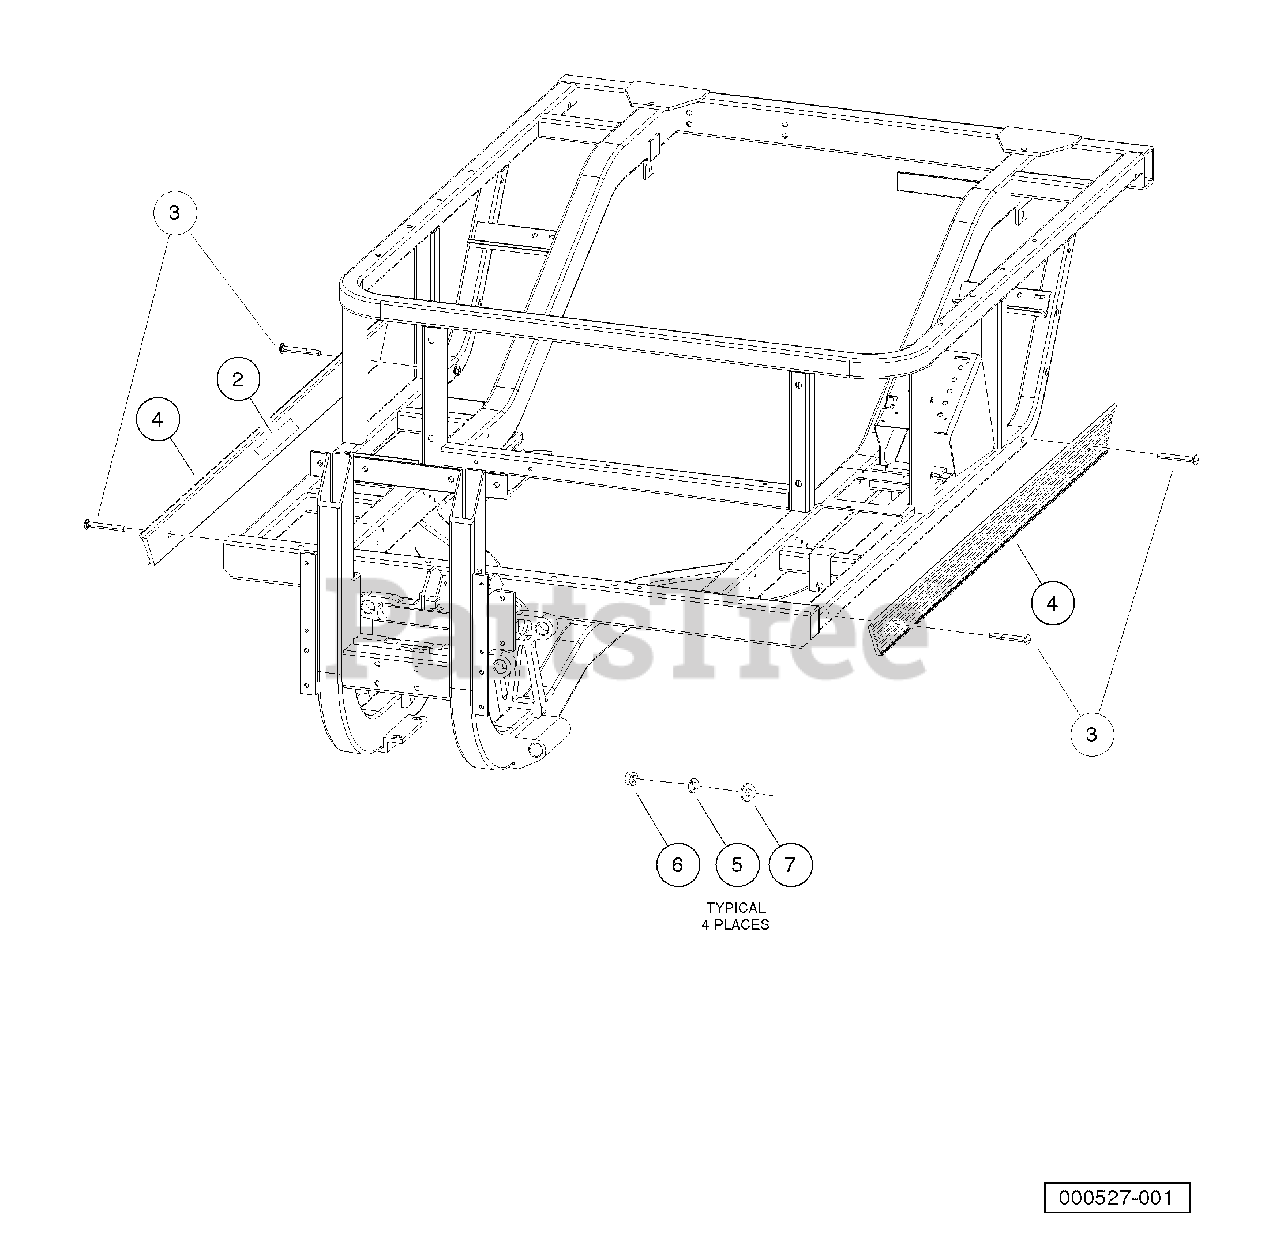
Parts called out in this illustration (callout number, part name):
1	Instl, Stringer, Black
2	Tape, 3M VHB 4950
3	Bolt, 3/8-16 X 3, Carriage Blk
4	Stringer, Side, 134925, Black
5	Washer, Lock, Hel Sp 3/8 Reg
6	Nut, Hex 3/8-16
7	Washer, 3/8 Type B Flat
